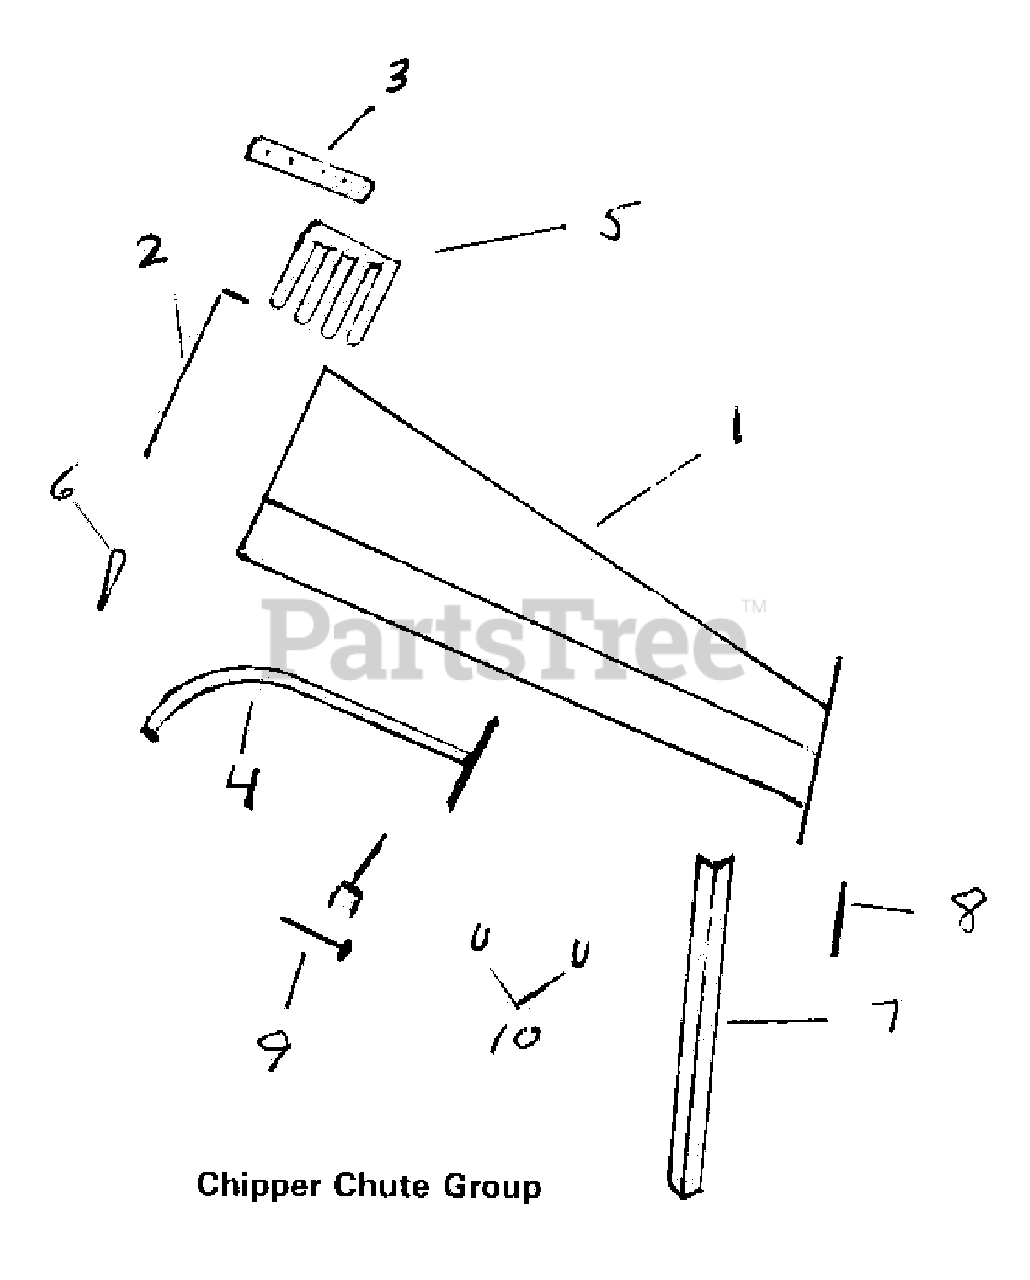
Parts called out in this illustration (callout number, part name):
1	Chipper Chute
2	Chipper Chute Door
3	Chipper Door Hinge
4	Chipper Chute Plunger
5	Rubber Deflector Flap
6	Rubber Tie Down
7	Chute Support
8	Bed Knife
9	Safety Holder
10	Plunger Holder
